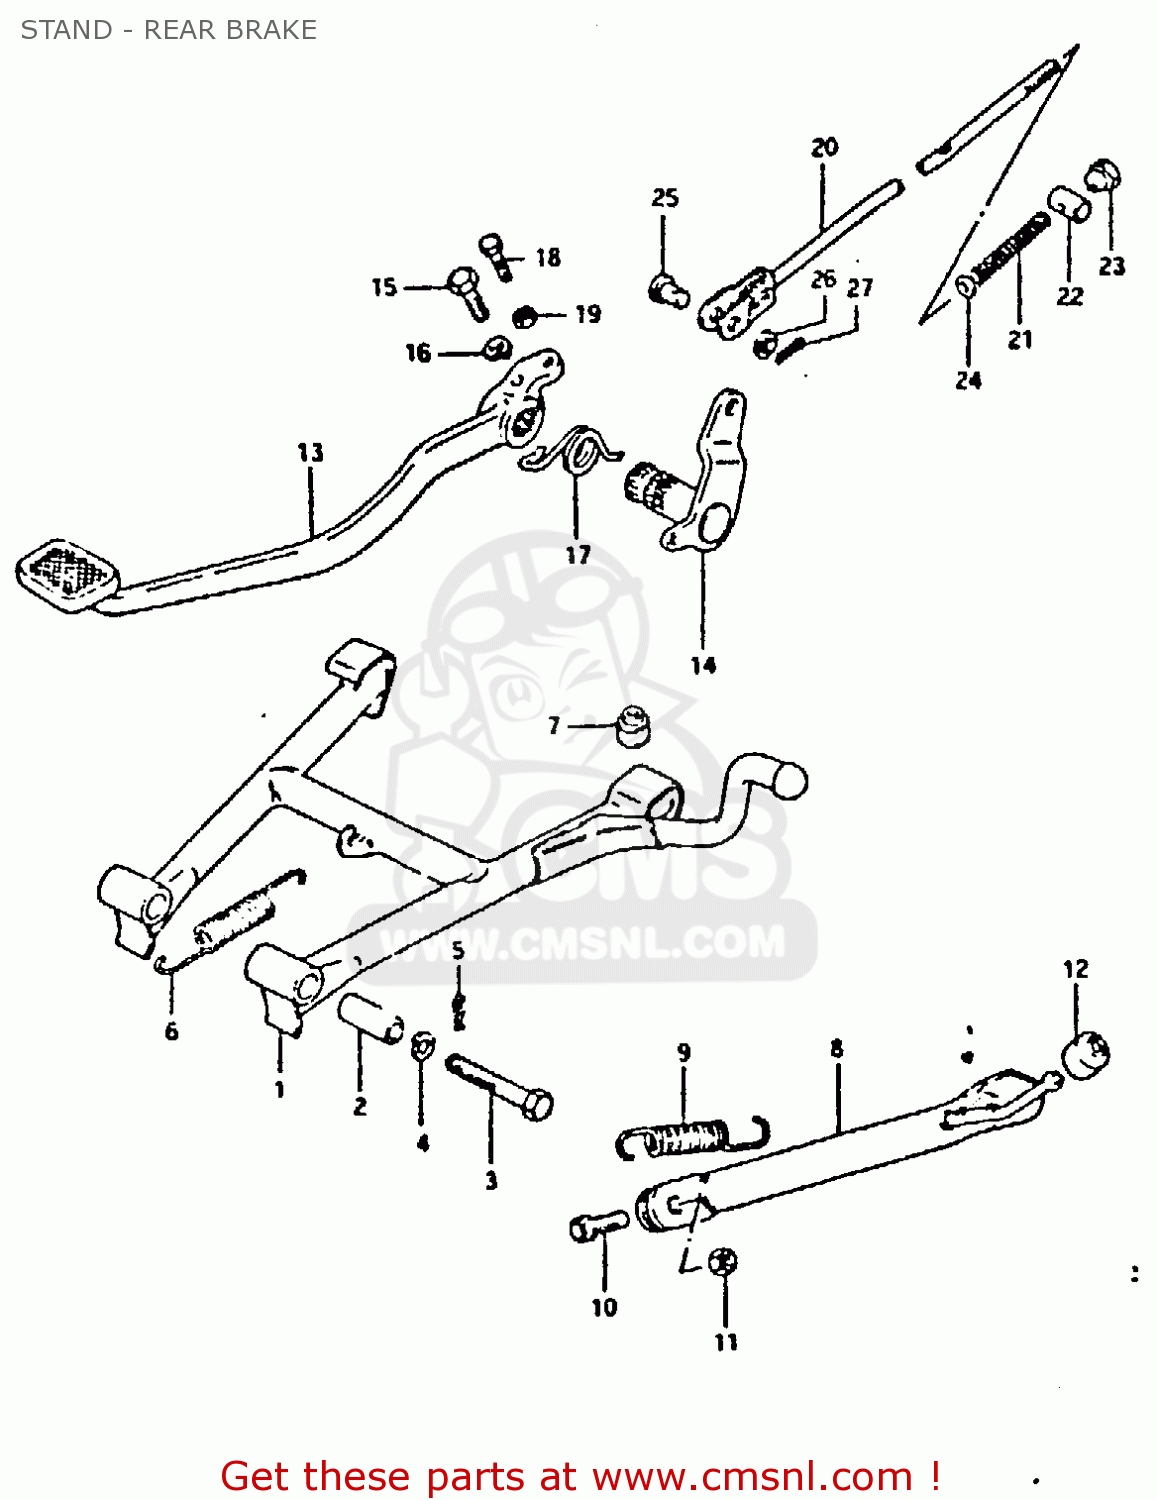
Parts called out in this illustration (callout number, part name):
1	STAND,CENTER
2	SPACER(10X16X38.8)
3	BOLT
4	LOCK WASHER
5	CLIP
6	SPRING
7	CUSHION(11.5X22X20)
8	STAND,SIDE
9	SPRING
10	BOLT(10X30)
11	NUT
12	CUSHION
13	PEDAL,BRAKE
14	ARM,BRAKE PEDAL ROD
15	BOLT
16	LOCK WASHER
17	SPRING
18	BOLT
19	NUT
20	ROD ASSEMBLY,REAR BRAKE
21	SPRING
22	PIN
23	NUT
24	WASHER
25	PIN(L:13.5)
26	WASHER
27	PIN 20X20
